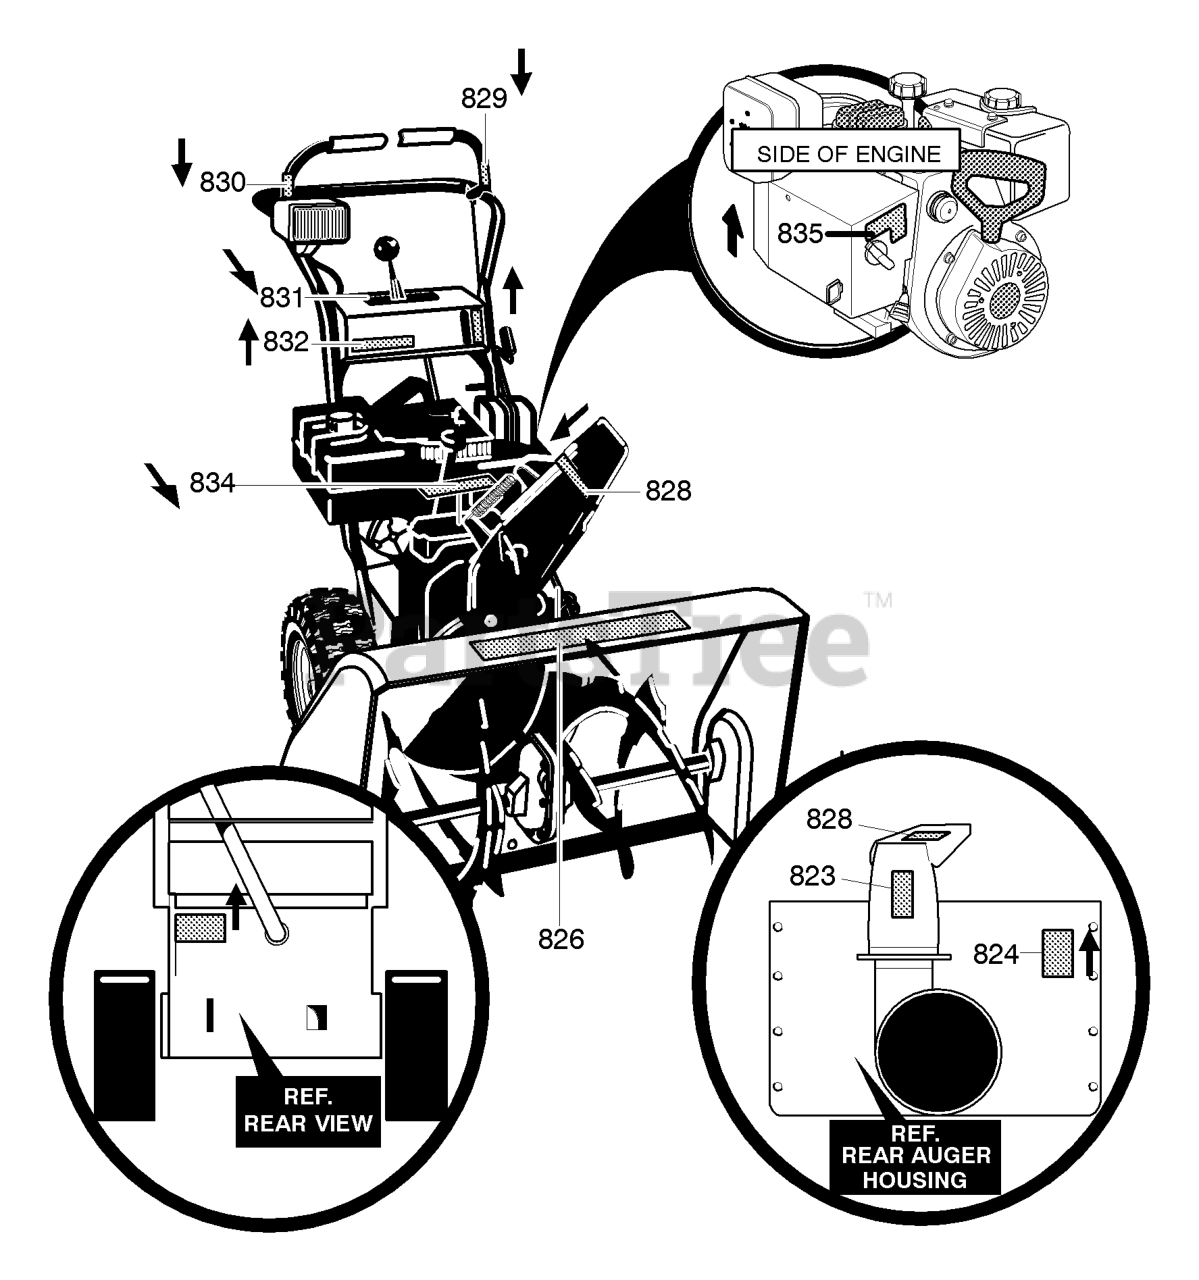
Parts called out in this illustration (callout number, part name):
823	DECAL, DANGER CHUTE HAND
824	DECAL, DANGER FOOT
826	DECAL, CRAFTSMAN 11/30
828	DECAL, THROWN OBJECTS
829	DECAL, DRIVE CLUTCH
830	DECAL, AUGER CLUTCH
831	DECAL, GEAR SELECTOR
832	DECAL, CRAFTSMAN
834	DECAL, TOOLBOX INFORMATION
835	DECAL, BRIGGS
